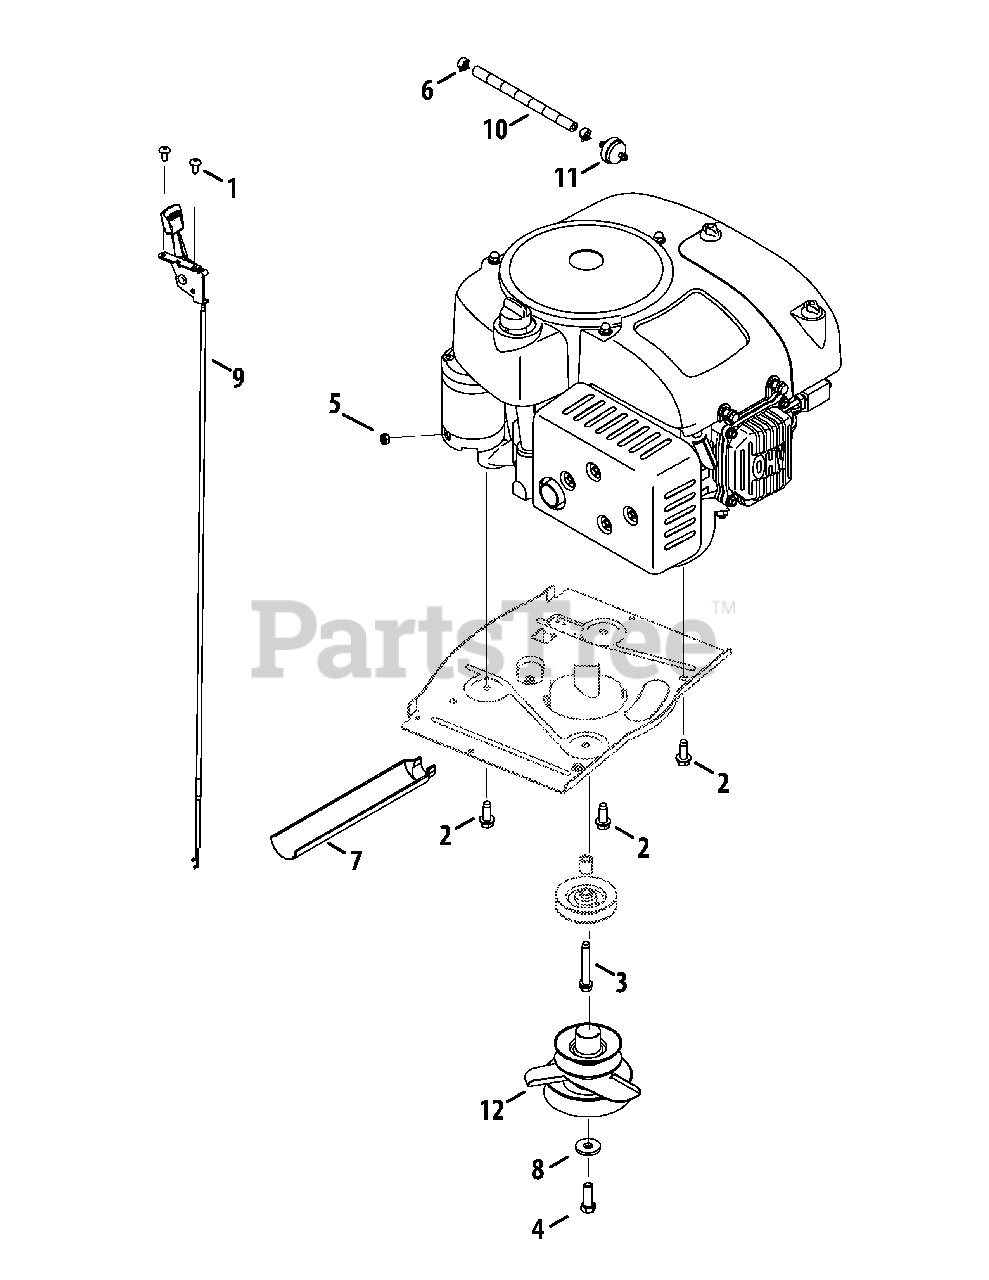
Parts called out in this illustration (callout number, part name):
1	Tap Screw, 1/4-20, 0.500
2	Tap Screw, 3/8-16, 1.000
3	Tap Screw, 3/8-16, 2.250
4	Hex Head Screw, 7/16-20 x 1.25
5	Nut, Hex Nylon Lock, M6-1.0
6	Hose Clamp, .490 DIA.
7	Oil Drain Sleeve
8	Flat Washer, .450 x 1.25 x .164
9	Throttle/Choke Cable 31 Lg.
10	Low Permeation Fuel Line, 1/4
11	Fuel Filter, 1/4", 298090
12	Engine Pulley, 4.46 / 3.39
